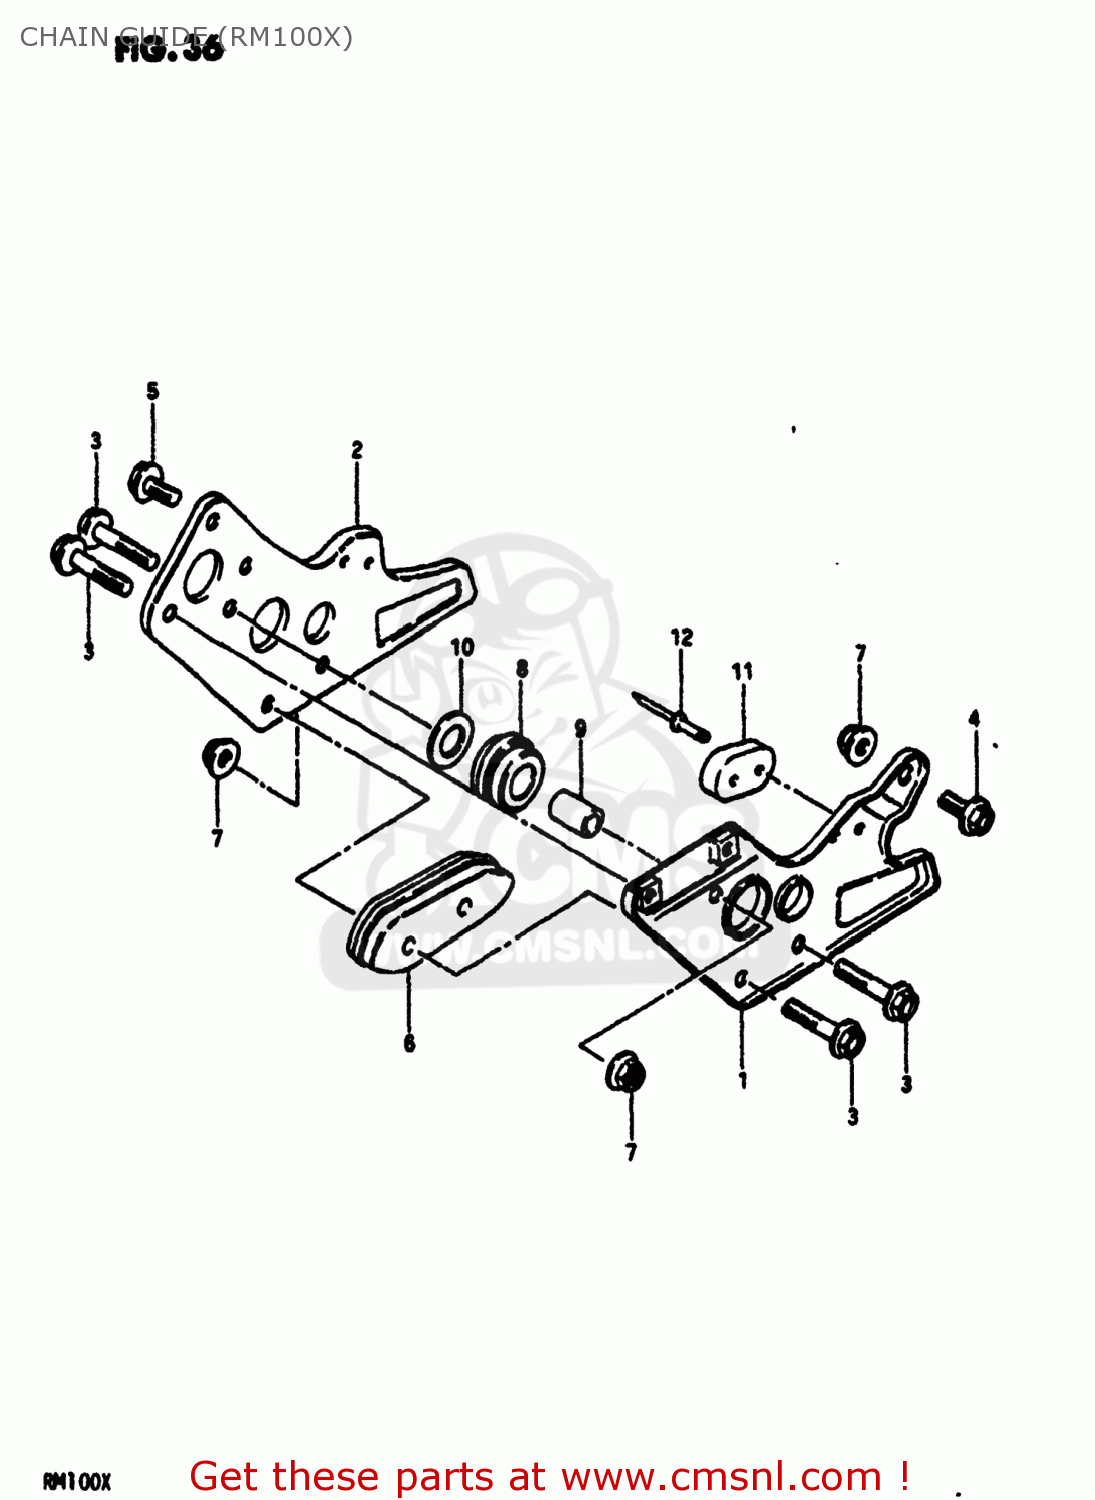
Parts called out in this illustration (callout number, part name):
1	PLATE,CHAIN GUIDE,OUTER
2	PLATE,GUIDE CHAIN
3	BOLT 6X35
4	BOLT
5	BOLT
6	DEFENSE,CHAIN GUIDE
7	NUT
8	ROLLER,CHAIN GUIDE
9	SPACER,CHAIN GUIDE ROLLER
10	WASHER
11	PAD,DRIVE CHAIN GUIDE
12	RIVET
